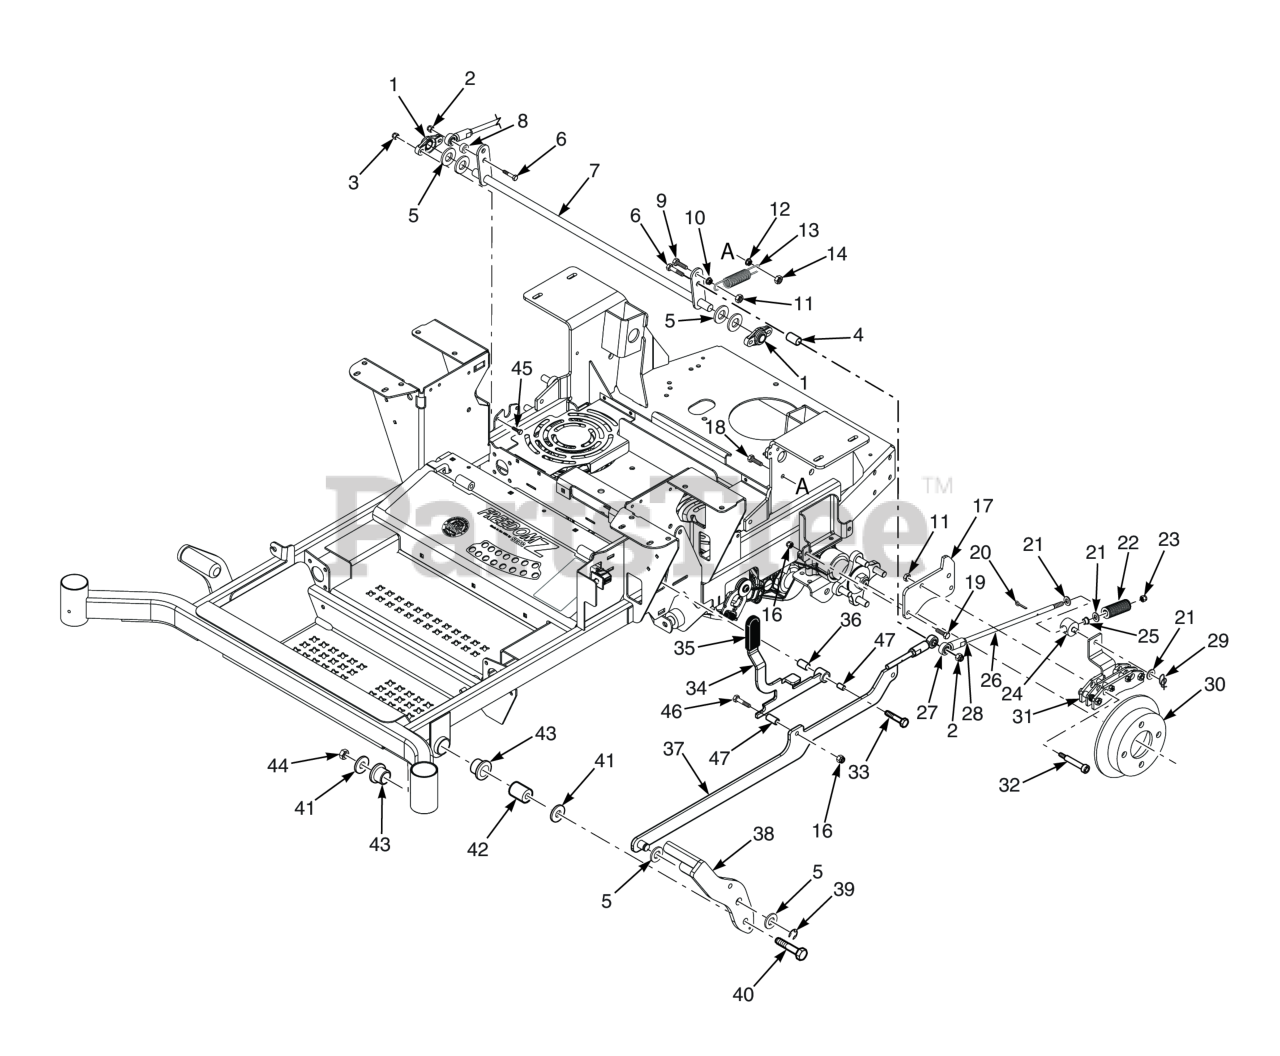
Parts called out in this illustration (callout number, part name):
1	Bearing
2	HEX NUT, ELASTIC STOP LOCK, 3/8-16
3	Nut, Flanged Elastic Stop 1/4-20
4	Spacer, Idler Pulley - SFZ61
5	Flatwasher, 5/8" (.656 x 1.312 x .095")
6	Bolt, Hex Head 3/8-16 x 2-1/4" - 61"
7	Weldment, Brake Lever
8	Spacer, Idler Pulley - SFZ52
9	Bolt, Hex Head, 3/8-16 x 1-1/2"
10	NUT, 3/8-16 SERRATED FLANGE HEX HEAD
11	Bolt, Hex Head 3/8-16 x 1" Ser. Flg.
12	Nut, Serrated Flange 5/16-18 (Right Front Engine Mounting, Briggs and Kohler Only)
13	Spring, Deck Lift
14	Nut, Center Lock, 5/16-18(32)
15	Flatwasher, 3/8" Special (.391 x .938 x .105)
16	HEX NUT, ELASTIC STOP LOCK, 5/16-18
17	Mounting Bracket, Brake
18	Bolt, Heax Head 5/16-18 x 1" (48V / 52V)
19	Bolt, Heax Head 5/16-18 x 1" (48V / 52V)
20	Pin, Cotter 3/32 x .75"
21	Flatwasher, 3/8 (.406 x .812 x .065)
22	Spring, Brake
23	Nut, Elastic Stop 3/8-16, grade 8 black
24	Swivel Assembly, Brake
25	Bearing
26	Link, Brake
27	Rod End, 3/8-24 RH Female
28	Nut, 3/8-24 UNF R.H. Thread
29	Pin, Rue Cotter 3/8" Diameter
30	Spacer, Axle
31	Brake Caliper
32	Bolt, Shoulder 1/2 x 2-1/2"
33	Bolt, Shoulder 1/2 x 2"
34	Latch Assembly, Brake
35	Grip, Brake Handle
36	Bearing
37	Linkage Weldment Assembly, Brake
38	Brake Pedal Weldment
39	RETAINING RING, 5/8" EXTERNAL "E"
40	Bolt, Hex Head 1/2-13 x 3"
41	Flat Washer, 1/2 (.562 x 1.375 x .109)
42	Spacer, Deck Lift Pivot
43	Bearing, Plastic
44	Locknut, Hex 1/2-13 Center Lock
45	CAP SCREW, 1/4-20 X 1" SERRATED FLANGE HEX
46	Bolt, Hex Head 5/16-18 x 1-1/2" - Front
47	Sleeve, Handle Pivot
